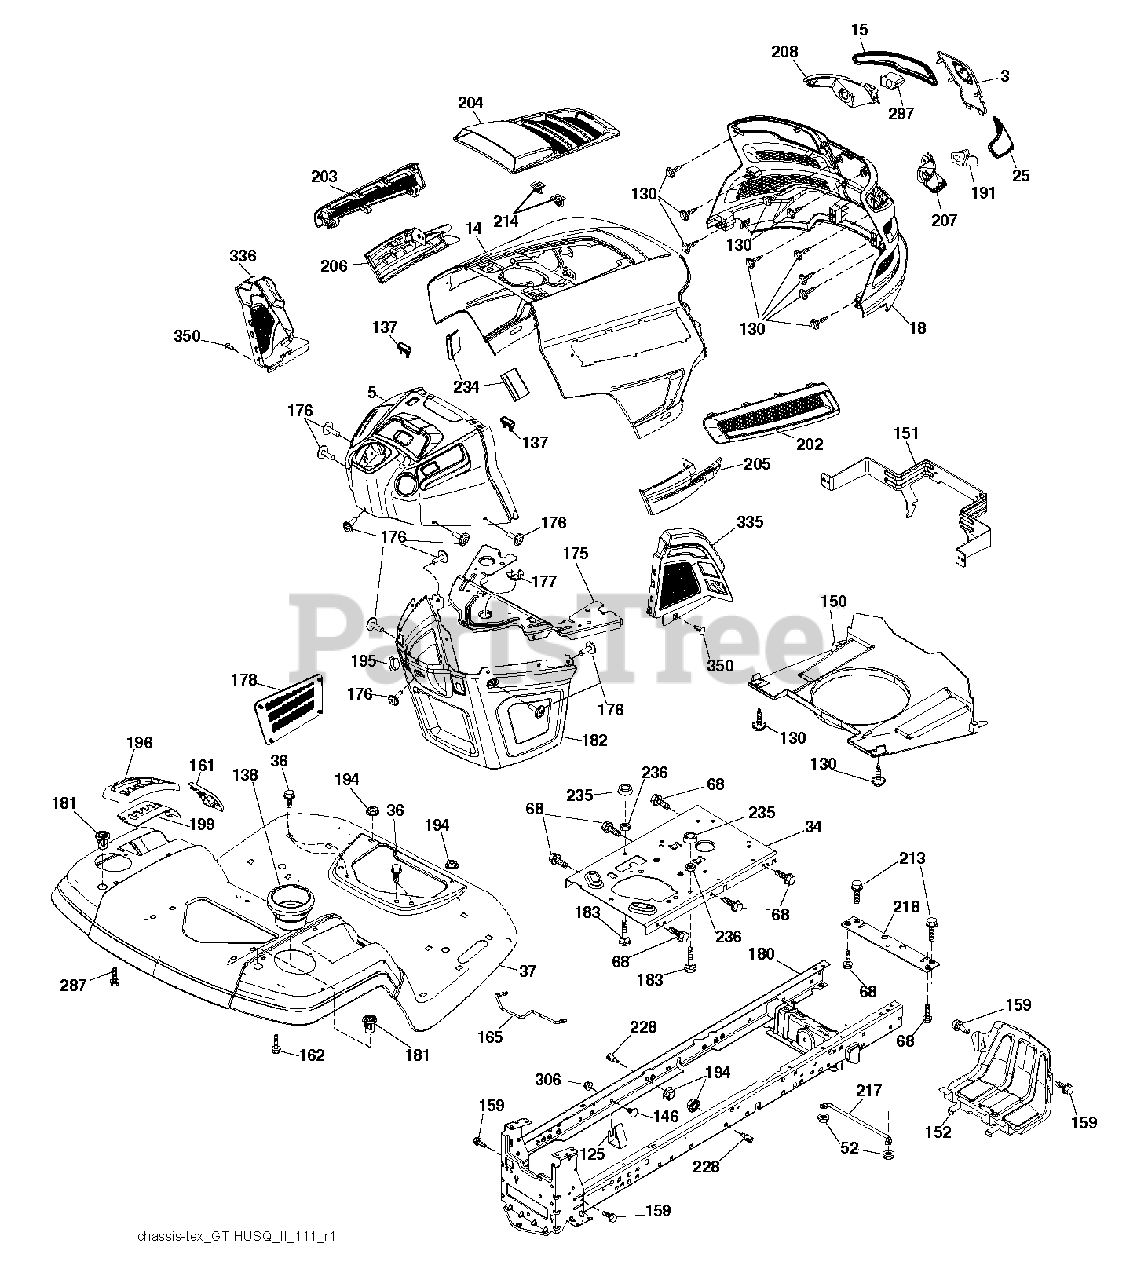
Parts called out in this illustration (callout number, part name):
3	APPLIQUE.SUBASM.GT.HUSQ.II
5	DASH.UPR.GT2.SRV.MIND.MAN.CLUT
14	HOOD.ASM.HUSQVARNA.GT.TEX.ORAN
15	LENS.HEADLIGHT.LH.GTII.2011
18	GRILLE.SUBSTRATE.2011.
25	LENS.HEADLIGHT.RH.GTII.2011
34	PLATE.ENGINE.WELDED.CHASSIS
36	SCREW 5/16"
37	FENDER.ERGO.LT.W/CPH.W/FW.ORNG
52	LOCKNUT
68	SCREW LT
125	CLIP.FUEL.LINE
130	SCREW.#10 X 0.750.BOS
137	BUMPER DASH
138	HOLDER.CUP.LT.GREY
146	BOLT.RDHD.SHT.SQNK.3/8-16X5/8
150	AIR DUCT.GTV2(1.66"RING HEIGHT
151	BRACKET.PIVOT.HOOD.GT.HUSQ.II
152	SHIELD.BROWNING.PNT.GT.V2
159	SCREW, 3/8-16X3/4
161	WINDOW.FUEL.LT.HUSQ.TEX.498
162	SCREW.HI-LO.CONSOLE
165	SUPPORT.TANK.REAR.W/TEX
175	PLATE.CROSSMEMBER.HUSQ
176	SCREW.#10-24X5/8.RN.QU
177	BUSHING, STEERING
178	CARGO.ASM.NET.TXGT.W/C
180	CHASSIS
181	BUSHING.MNT.FEND.CRGO.TEX.49
182	DASH.LOWER.COMMON.12V.ADAPTOR
183	BOLT.5/16-18X1-1/4 FULL THD
191	INSERT.REFLECTIVE.RH.HUSQ.GTII
194	NUT LOCK HEX FLANGE 5/16-18
195	PLUG.HOLE.DASH.LOWER.12V.BLK
196	DECKLFT.CONSOL FULL ASSM GREY
199	PLATE.DECK.LIFT.HUSQ.LT
202	VENT.SIDE.RH.GT.HUSQ.II.
203	VENT.SIDE.LH.GT.HUSQ.II.498
204	VENT.TOP.ASM.HUSQ.GT2
205	SIDE.TRIM.RH.GT.HUSQ.II
206	SIDE.TRIM.LH.GT.HUSQ.II.GRAY
207	BEZEL LIGHT.RH.GT.II.MYLAR
208	BEZEL LIGHT.LH.GT.II.MYLAR
213	BOLT
214	CLIP.RETAINER.TINNER.
217	ROD.PIVOT.HOOD
218	X-PIECE.HOOD.STOP.NON/
228	STUD.FASTNER.W/ANTI-ROTATE
234	BUMPER.HOOD.TEX.HUSQVARNA
235	SPACER FENDER
236	NUT.CENTERLOCK.5/16-
287	SCREW 1/4X20
297	INSERT.REFLECTIVE.LH.HUSQ.GTII
306	NUT LOCK FLG 3/8-16 UNC
335	COVER.LOWER.DASH.RH.BLACK
336	COVER-LH.LOWER.DASH.GT2.BLACK
350	CLIP.X-MAS.TREE
